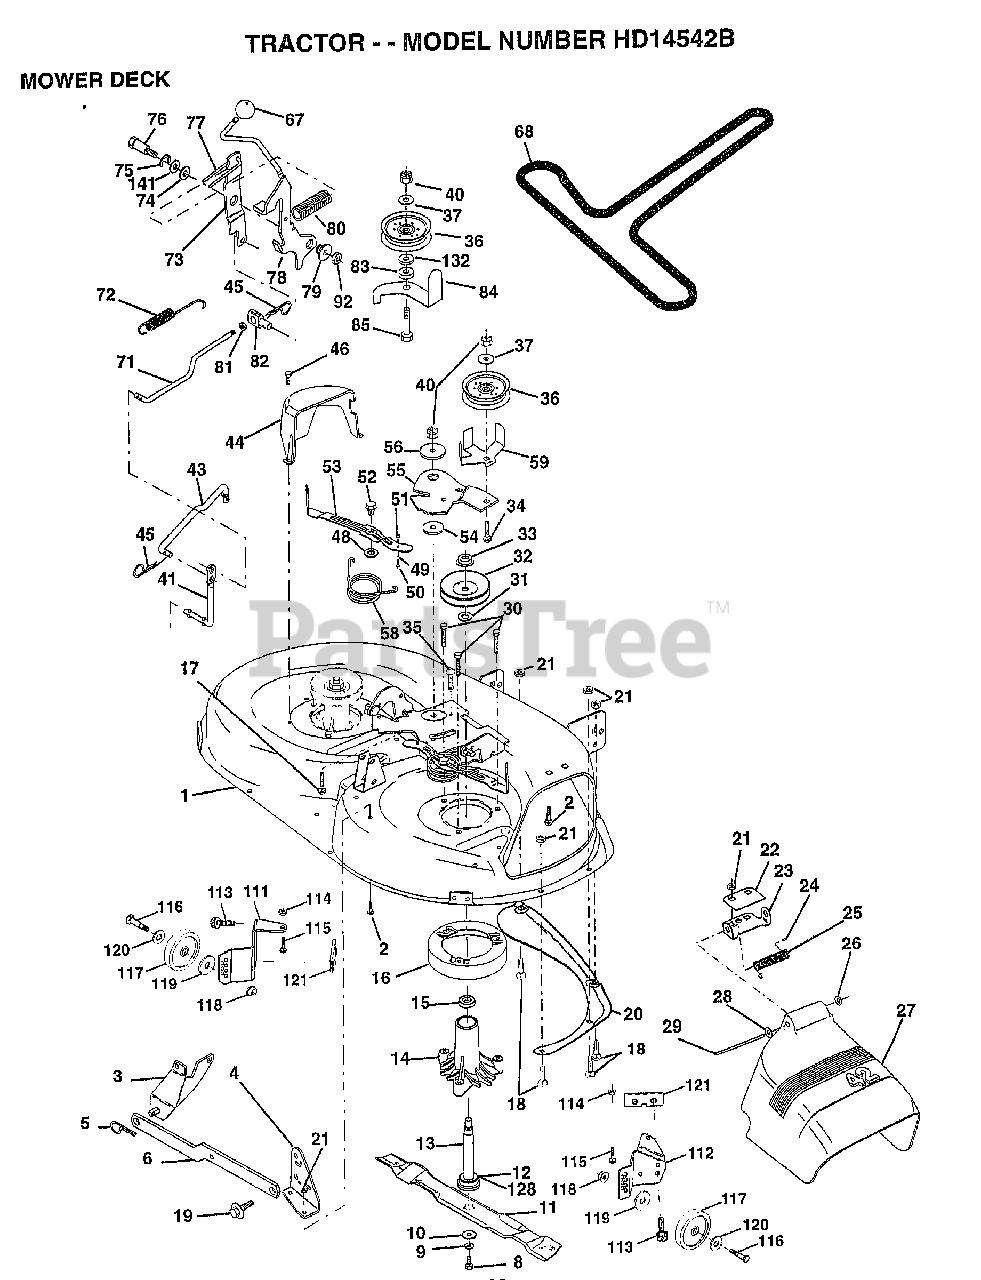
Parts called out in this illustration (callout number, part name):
1	"HOUSING ASSY.42"""
2	BOLT
3	BRKT ASM SWAY BAR
4	BRKT DECK SW BAR
8	BLADE BOLT
10	WASHER.HARD.BLADE
11	"BLADE.42"" HIPERF"
12	BEARING.BALL
14	HSG ASM MANDREL
15	BEARING
16	STRIPPER RND MWR
17	BOLT RDHD 3/8-16
18	BOLT
19	BOLT SHD 5/16-18
20	BAFFLE VORTEX 42
22	STIFFENER BRKT
23	DEFLECTOR BRKT
24	CAP-SLEEVE LT
25	SPRING TORSION
26	NUT PUSH M
27	DEFLECTOR.SHIELD
28	WASHER
29	HINGE ROD
30	"SCREW-THD ROLL,WA"
31	WASHER
32	PULLEY.MANDREL.42
34	BOLT
35	XMAS TREE FASTNER
36	FLAT IDLER PULLEY
37	WASHER
41	PIVOT ROD
43	ROD CLUTCH W/NIBS
44	GUARD MAND LH BLK
45	RETAINER M
46	SCREW.1/4-20X5/8
48	HARD SMALL WASHER
49	ROLLER ASM-CAM
50	SHOULDER BOLT
51	LOCKNUT
52	BOLT.SHLD.5/16-18
53	BRAKE PAD ARM ASM
54	HARDENED WASHER
55	ARM-IDLER
56	SPACER RETAINER
58	SPRING TORSN BRAK
59	GUARD IDLER TUV
67	KNOB.RD.7/16-14
68	BELT.V.T-PATH
71	ROD CLUTCH 38/42
72	RETURN SPRING
73	CLUTCH ARM SECOND
74	WASHER
75	RING
76	SHOULDER BOLT
77	SPRING KEEPER
78	LEVER.ASM.CLUTCH
79	BUSHING
80	SPRING.CLUTCH.MWR
81	NUT
82	TRUNION ADJ
83	WASHER
84	"KEEPER-BELT,FIXED"
85	BOLT
92	NUT
111	BRACKET.GWHL.LH.
112	BRACKET.GWHL.RH.
113	SCREW
116	BOLT M
117	WHEEL.GAGE.BLK.PL
118	LOCKNUT
119	WASHER
120	WASHER
121	BRACKET.EXTRD.GWL
128	WASHER.FELT.
132	WASHER GT
141	WASHER .T
